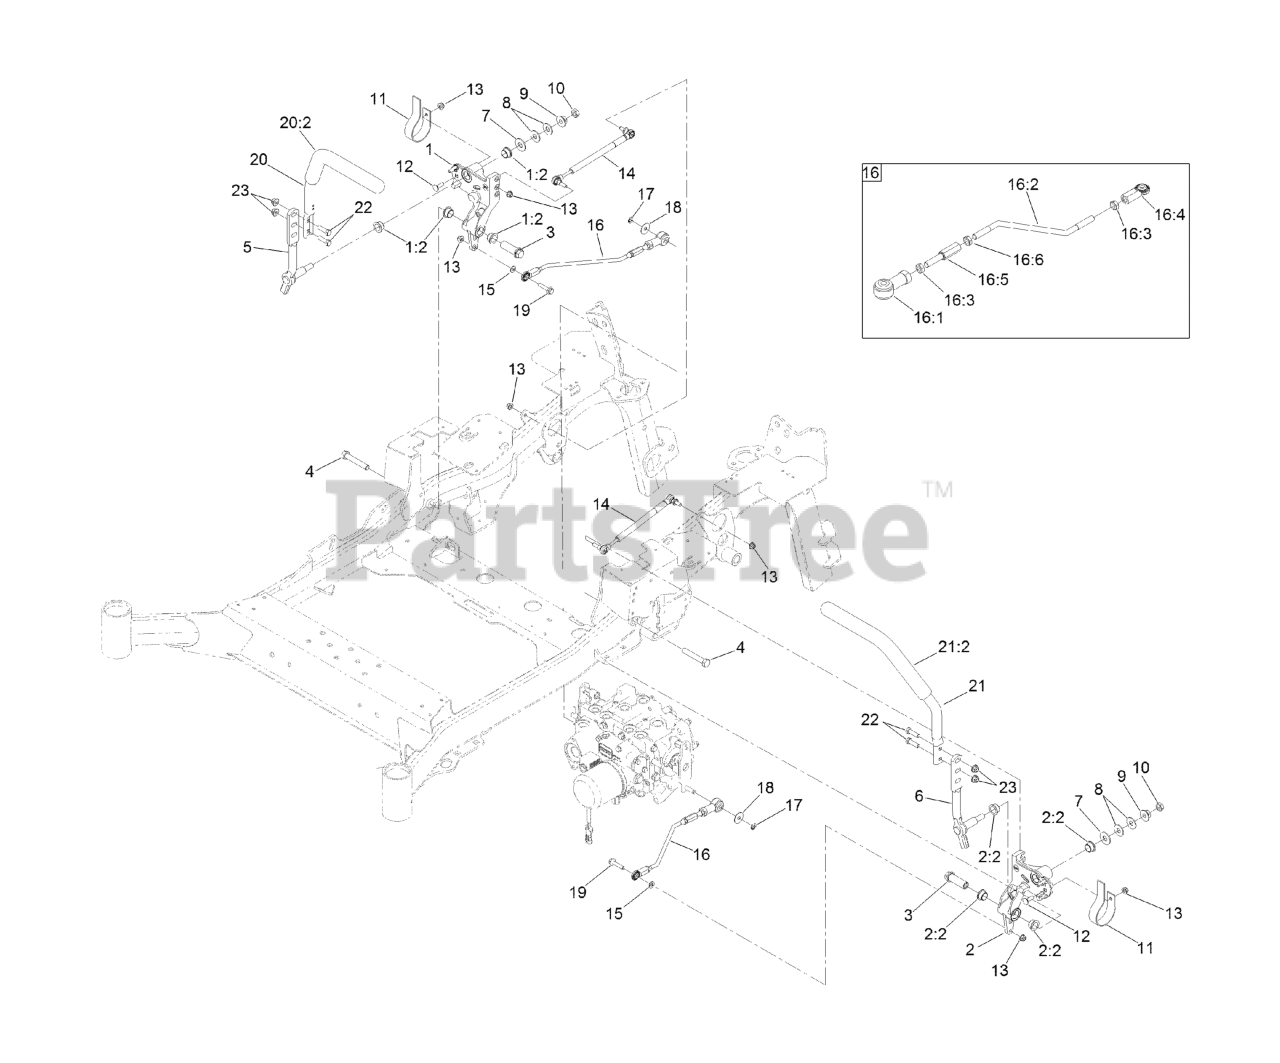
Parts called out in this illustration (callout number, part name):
1	RH MOTION CONTROL AND BUSHING ASM
1:2	BUSHING-FLANGE
2	LH MOTION CONTROL AND BUSHING ASM
2:2	BUSHING-FLANGE
3	HUB-THREADED
4	SCREW-HH
5	LEVER-CONTROL MOTION, RH
6	LEVER-CONTROL MOTION, LH
7	WASHER-FLAT
8	WASHER-SPRING
10	NUT-JAM
11	SPRING-LEAF
12	BOLT-CARR
13	NUT-HF, NI
14	DAMPER-CONTROL, MOTION
15	WASHER-PLAIN
16	FRONT LINKAGE ROD ASM
16:1	END-ROD, ISOLATED
16:2	ROD-LINKAGE, REAR
16:3	NUT-HJ
16:4	JOINT-BALL, END
16:5	ROD-ADJUSTMENT
16:6	NUT-HEX JAM, LH
17	RING-RETAINING
18	WASHER-PLAIN
19	SCREW-HHF
20	RH STEERING HANDLE ASM
20:2	GRIP-LEVER, CONTROL
21	LH STEERING HANDLE ASM
21:2	GRIP-LEVER, CONTROL
22	SCREW-HH
23	NUT-HF, NI
